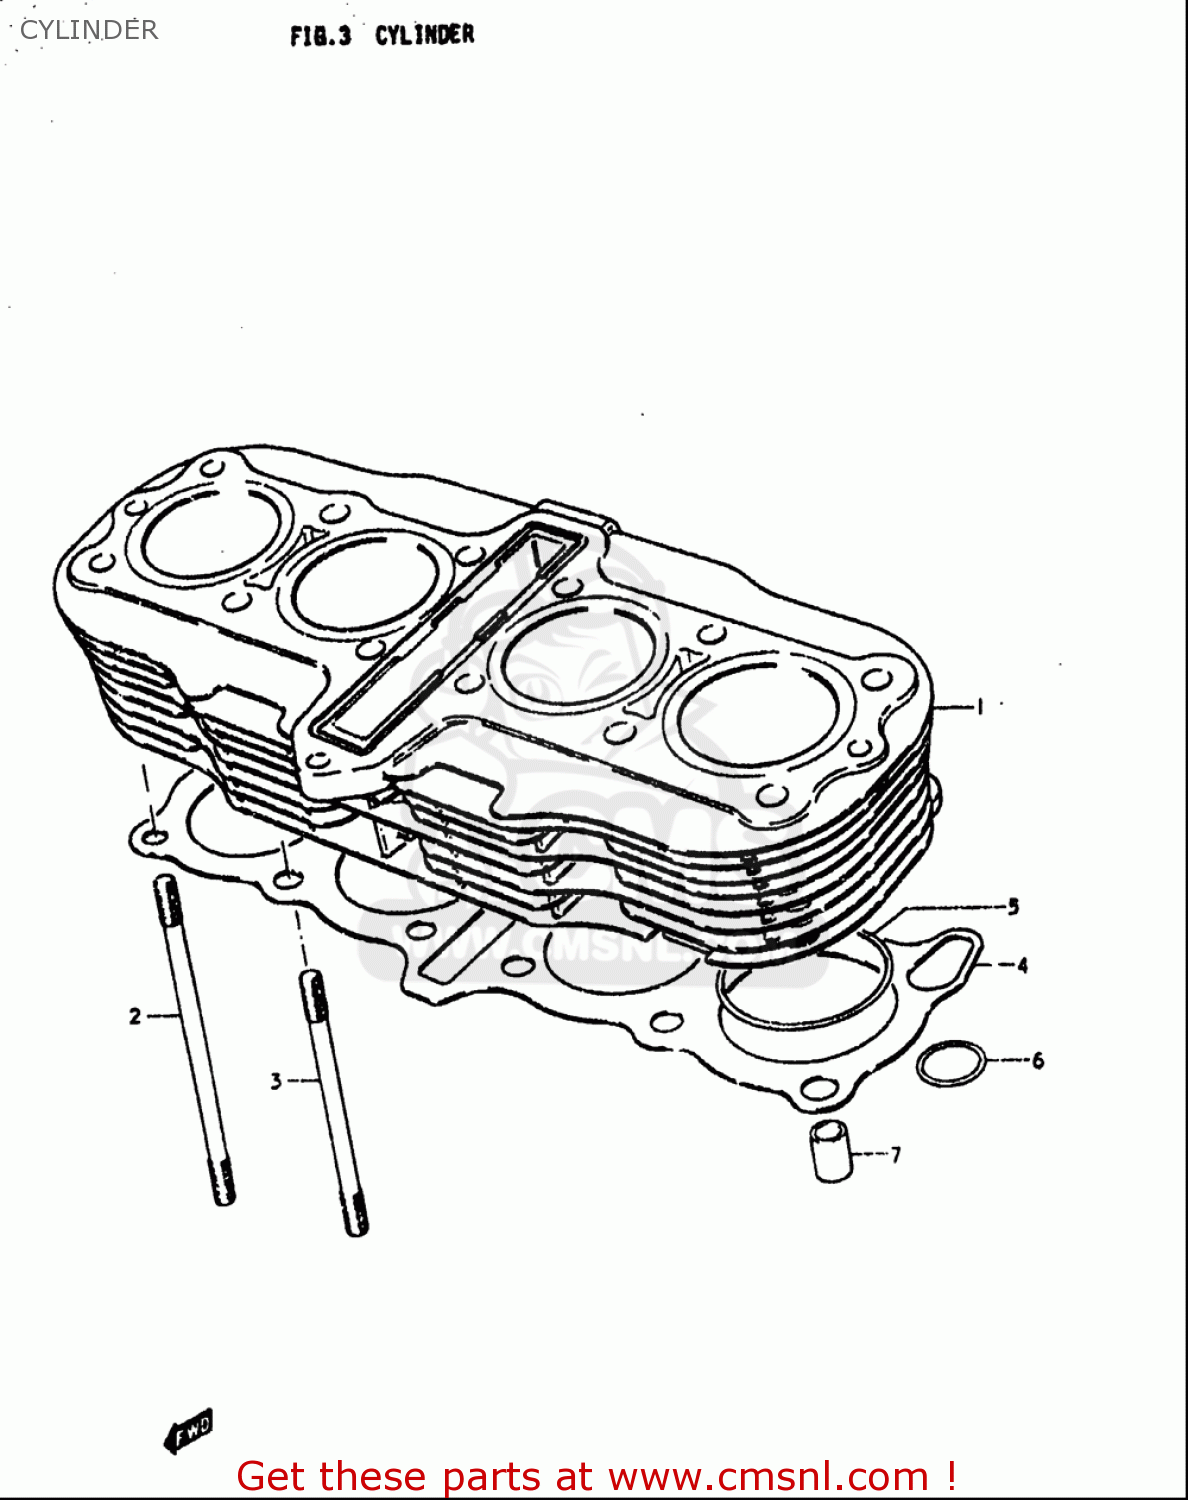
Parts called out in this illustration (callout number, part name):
2	BOLT,STUD
3	BOLT,STUD
4	GASKET,CYLINDER (NAS)
5	O RING(D:2,ID:74)
6	O RING(D:3.05)
7	PIN
